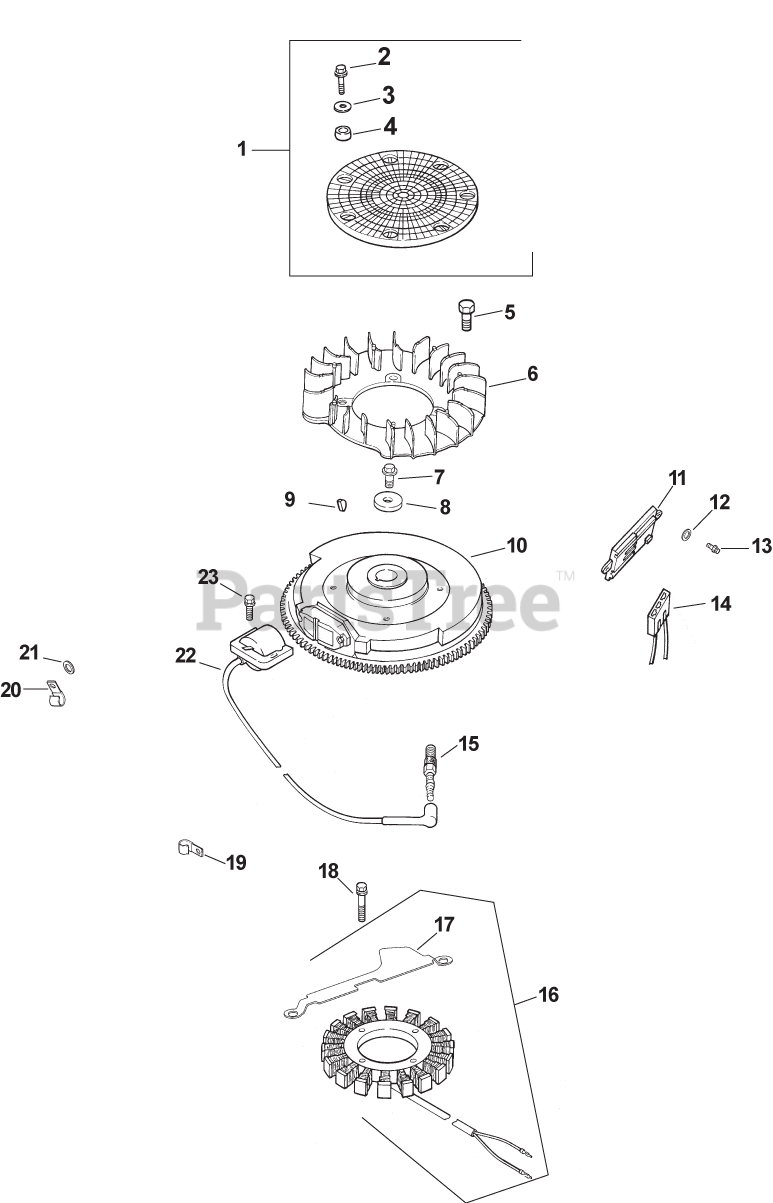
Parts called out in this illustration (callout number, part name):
1	KIT, GRASS SCREEN
2	SCREW, SLT HD CAP M4X0.7X25
3	WASHER, FLAT 3/16"
4	SPACER - DISCONTINUED
5	BOLT, SHOULDER
6	FAN (DOMED)-USE 24 157 17-S
7	SCREW, FLG M10X1.5X45 - (#25086361S)
8	WASHER, FLAT 13/32"
9	KEY, 3/16" X 5/8"
10	FLYWHEEL, PAINTED-USE 24 025 55-S
11	REG/RECT-15 AMP (KM)-USE 41 403 10-S
12	WASHER, FLAT 3/16"
13	SCREW, PHL HD #11-16X7/8"
14	CONNECTOR, BODY (KM)-USE 25 155 41-S
15	PLUG, SPARK (STD)
16	STATOR KIT - USE 237878-S
17	BRACKET, STATOR WIRE
18	SCREW, M5X0.8X25 - (#25086402S)
19	CLIP, CABLE
21	WASHER, FLAT 1/4" (O.D. 1/2")
22	MODULE, IGNITION-USE 24 584 45-S
23	SCREW, FLG THD FRM M5X.8X20-(#25086399S)
